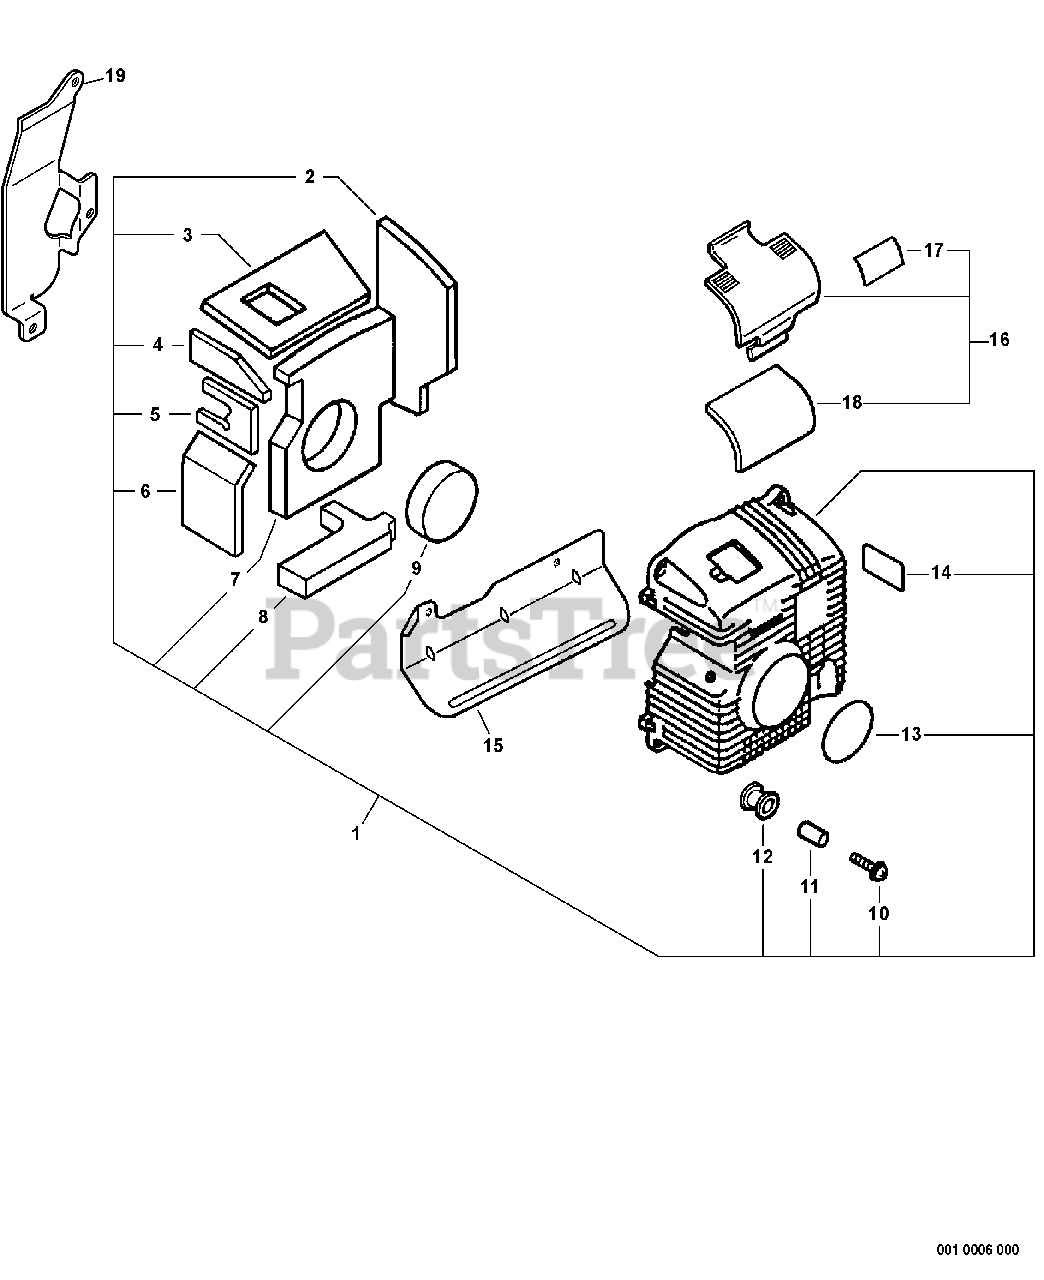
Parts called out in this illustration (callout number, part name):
1	ENGINE COVER KIT
2	PAD, FOAM - RIGHT
3	PAD, FOAM - TOP
4	PAD, FOAM - LEFT TOP
5	PAD, FOAM - LEFT CENTER
6	PAD, FOAM - LEFT BOTTOM
7	PAD, FOAM - REAR
8	PAD, FOAM - BOTTOM
9	PAD, FOAM - CENTER REAR
10	SCREW - 5X25
13	LABEL - ECHO
14	LABEL - HOT SURFACE
15	DEFLECTOR, HEAT
16	SPARK PLUG COVER ASSY
17	LABEL - HOT SURFACE
18	PAD, FOAM
19	INSULATOR
